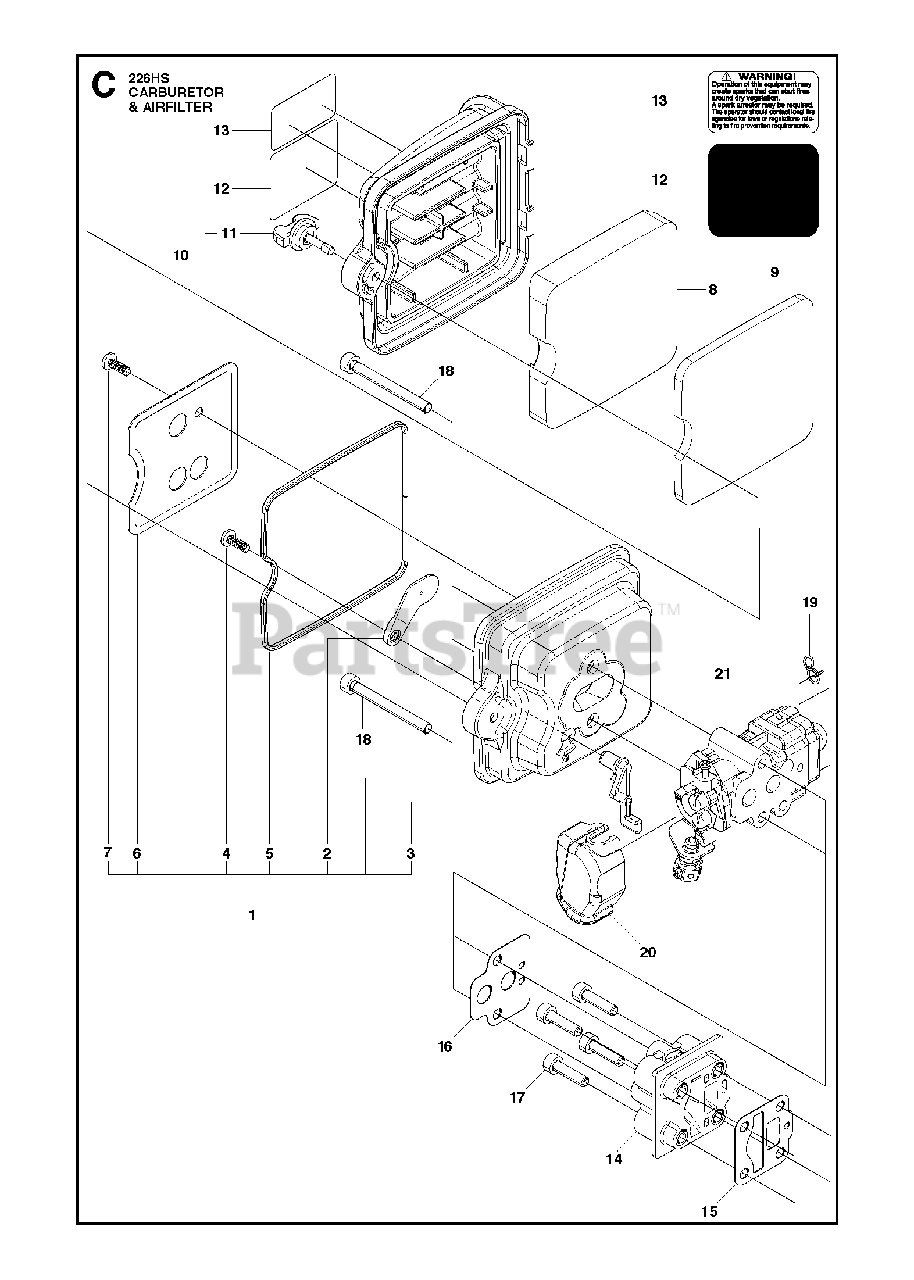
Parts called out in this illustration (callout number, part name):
2	PLATE.CHOKE
3	LEVER CHOKE
4	SCREW
5	PACKING
6	SCREEN
7	SCREW
8	FILTER FOAM
10	COVER ASSY
11	KNOB
13	LABEL
15	INSULATOR GASKET(R-848F0814B0)
16	GASKET, CARB (RPLS T155113131)
21	CARBURETOR ASSY
